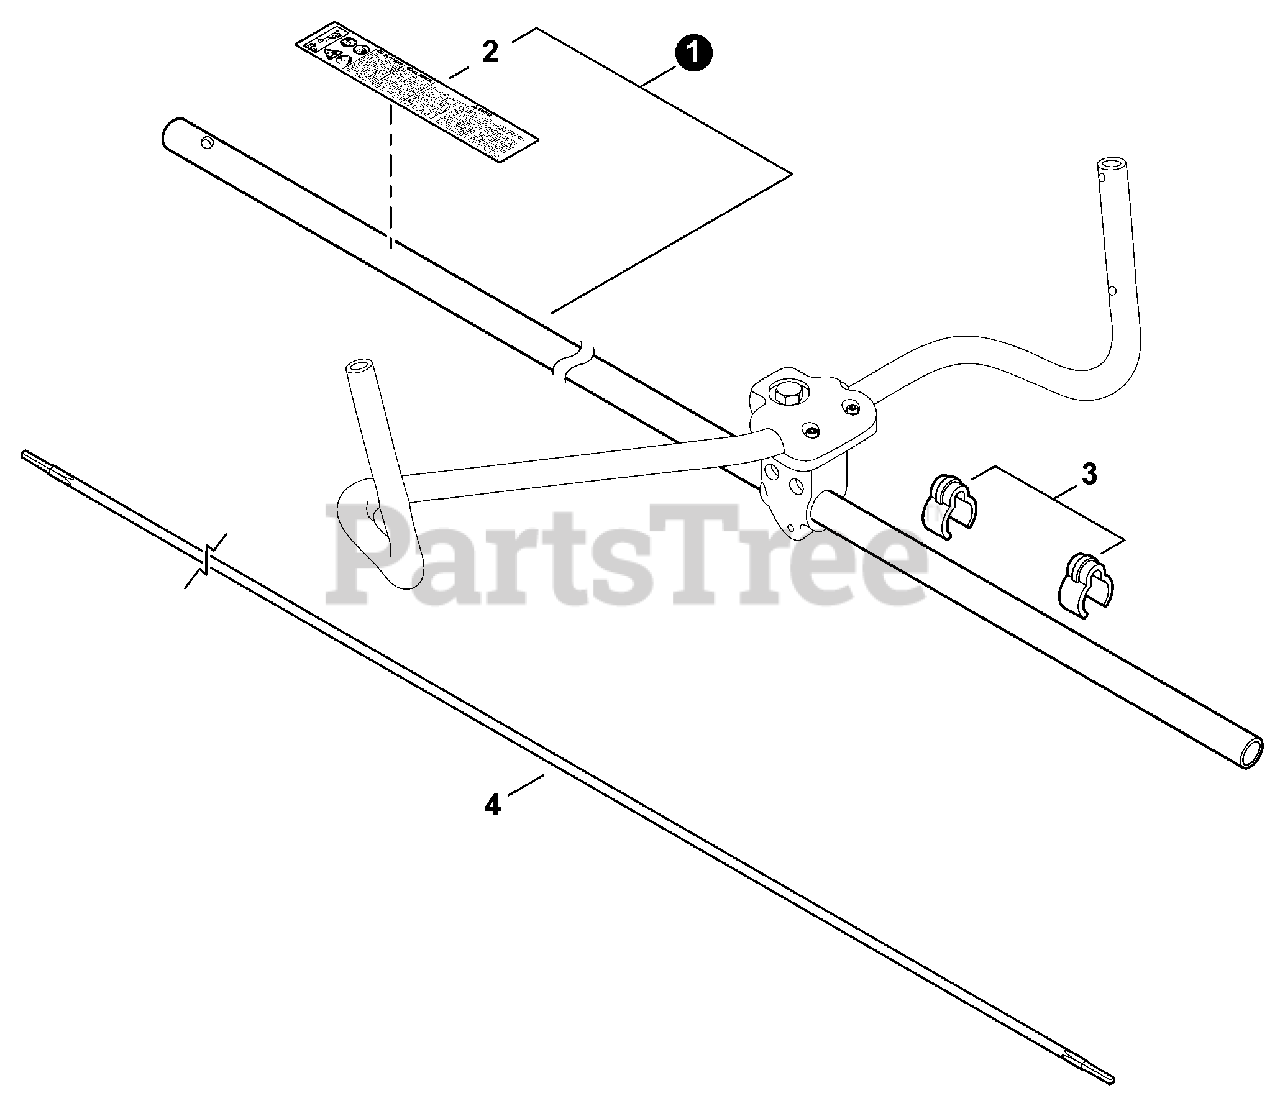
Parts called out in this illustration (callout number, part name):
1	MAIN PIPE ASSY
2	LABEL, CAUTION
3	CLIP, CABLE 25MM
4	DRIVESHAFT
